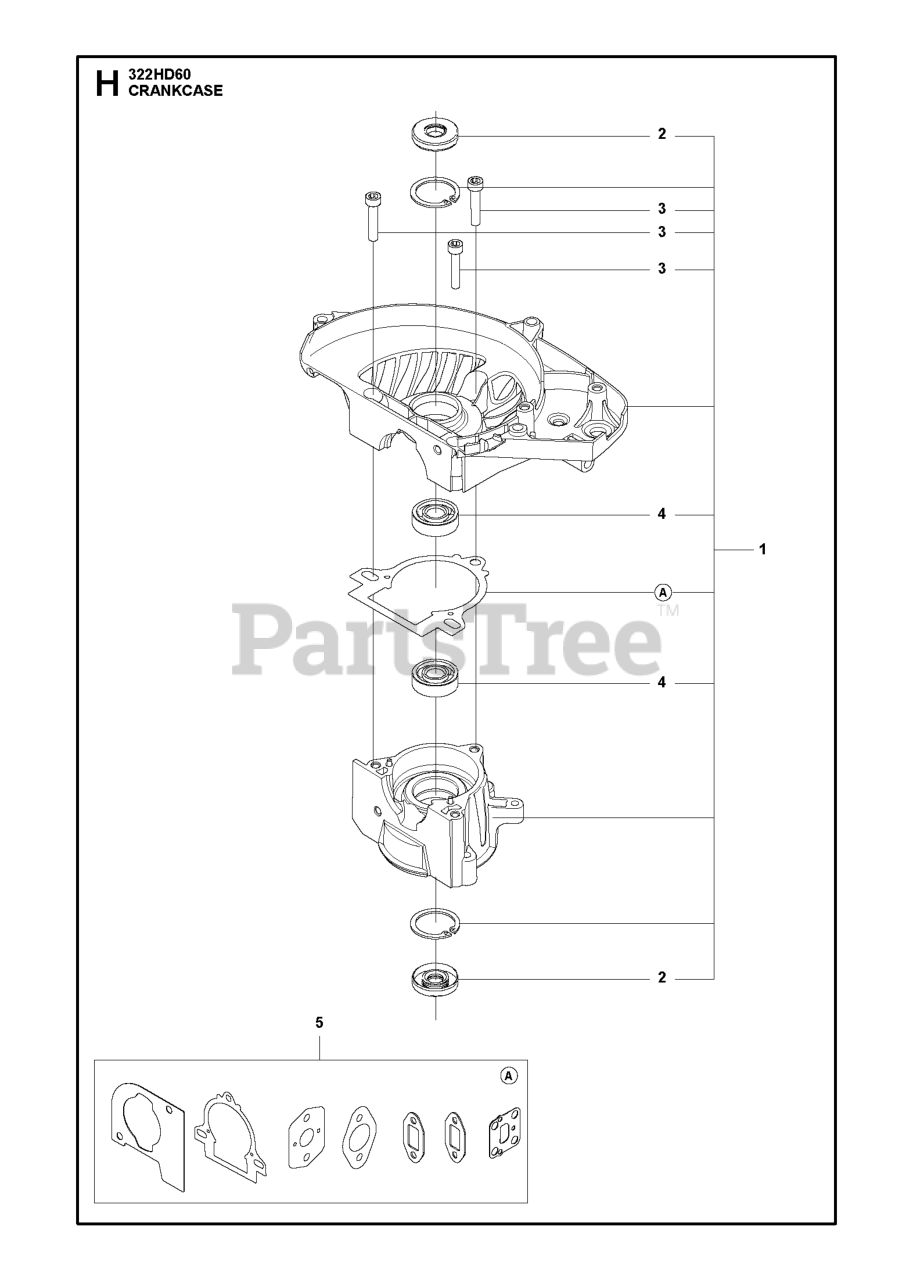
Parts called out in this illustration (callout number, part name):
1	Crankcases
2	SEALING RING
4	BALL BEARING
